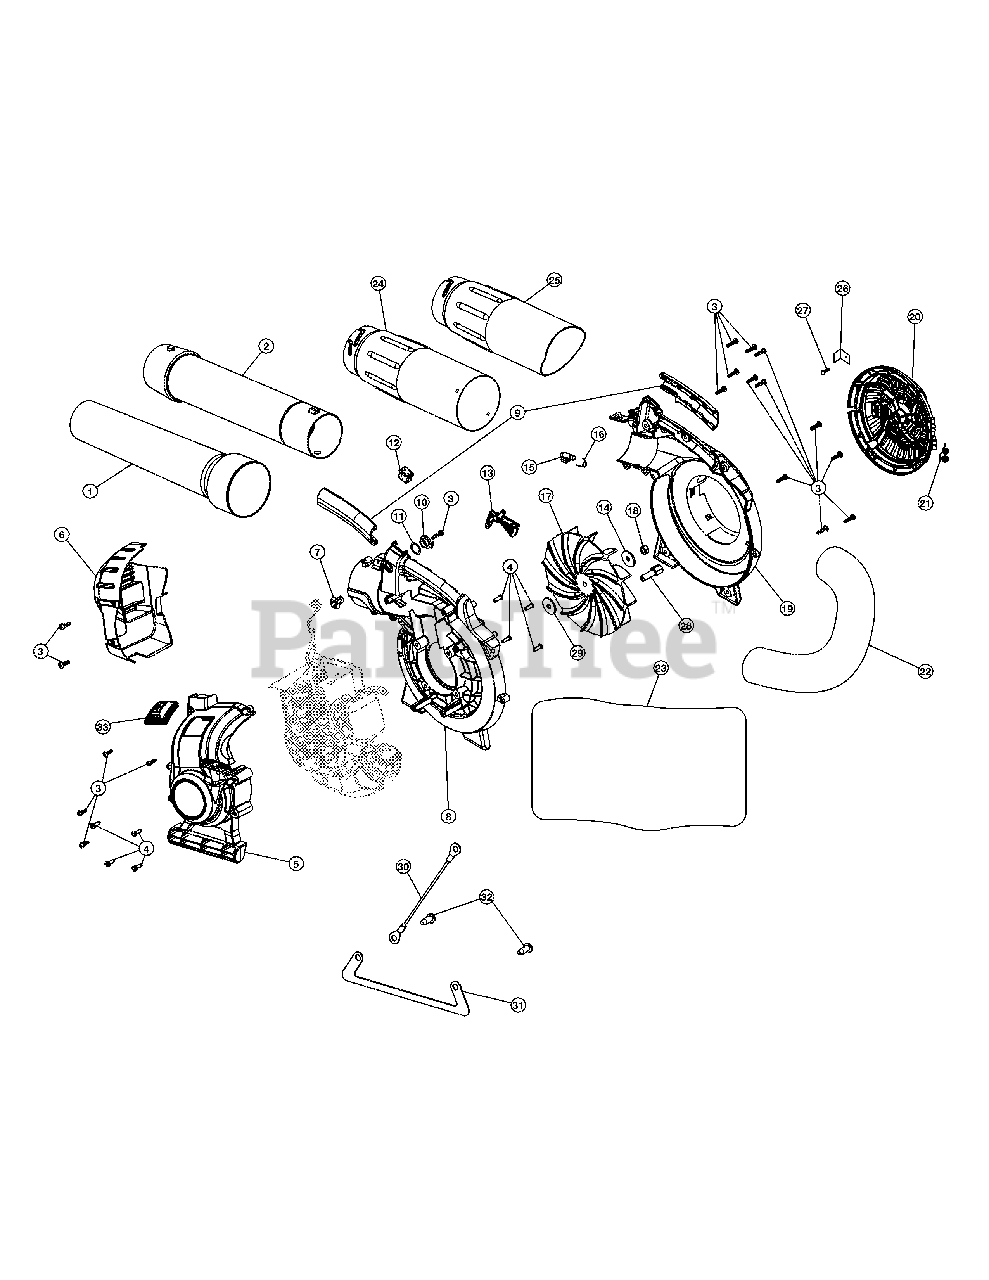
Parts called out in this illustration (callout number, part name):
1	Lower Tube
2	Upper Tube
5	Engine Cover Assembly
6	Muffler Cover Assembly
7	Outer Trigger Lock
8	Impeller Housing
9	Handle Grips
10	Inner Trigger Lock
11	Wavey Washer
13	Throttle Trigger
15	Latch Tube
16	Latch Spring
18	Nut
19	Impeller Housing
20	Intake Cover
24	Upper Vac Tube
25	Lower Vac Tube
27	Screw
30	Wire Ground
31	Strap Ground
32	Screw
33	Spark Plug Cover
